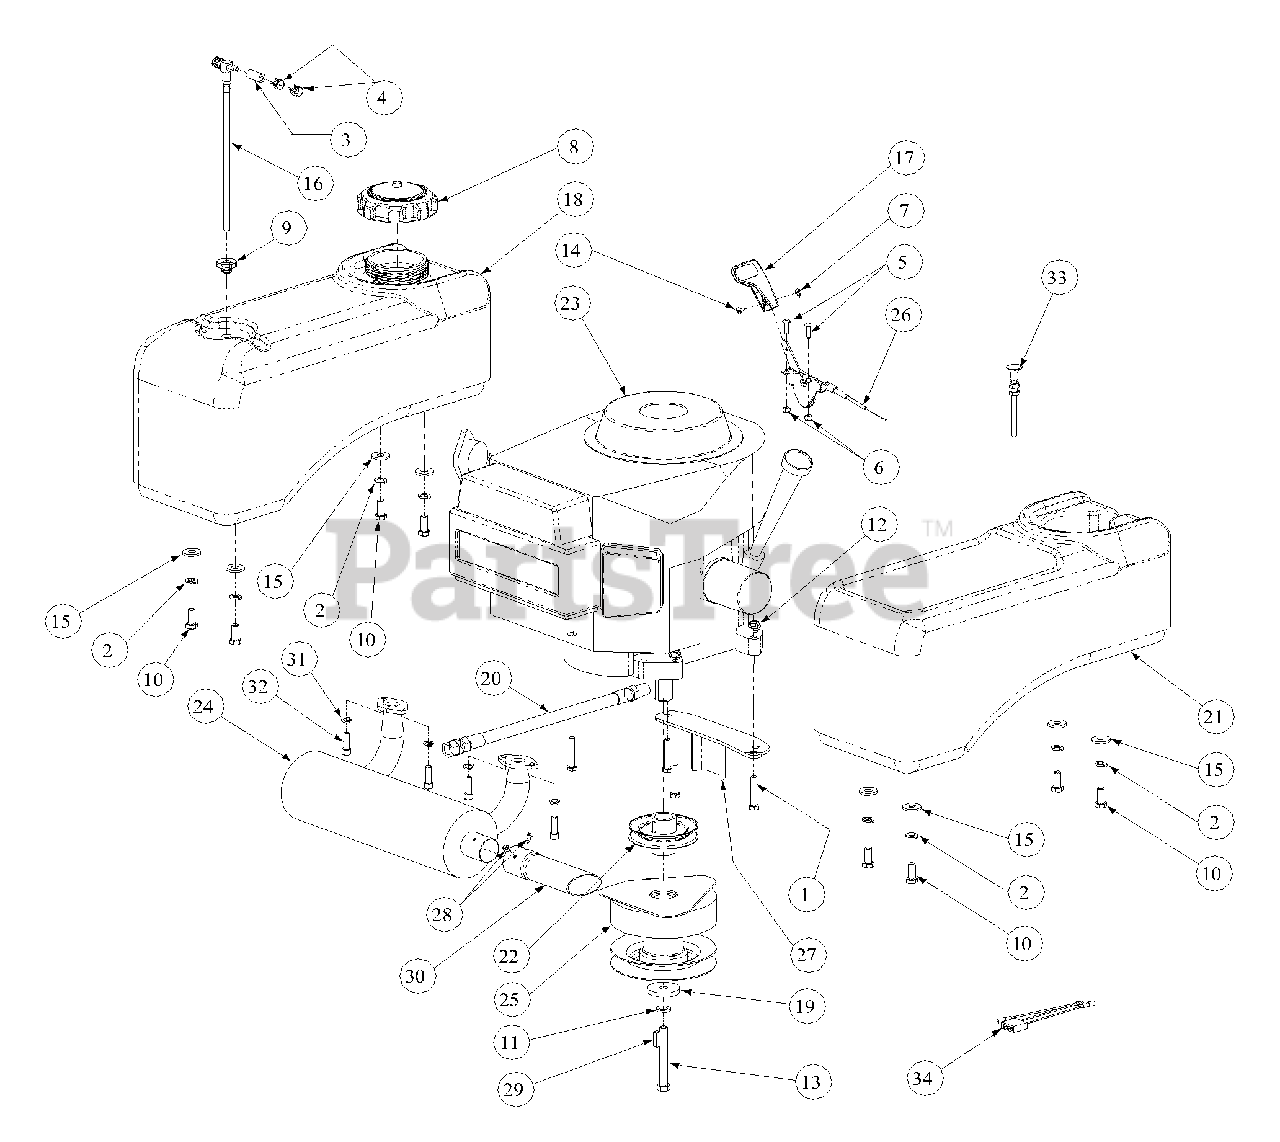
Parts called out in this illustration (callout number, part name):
1	Hex Head Cap Screw, 5/16-18 x 1-3/4
2	Lock Washer, 3/8 Zinc
3	Hose, 1/4" Fuel Line
4	Clamp, Union
5	Round Head Machine Screw, 10-32 x 3/4
6	Lock Nut, Nylon Insert, 10-32
7	Nut, w/ Star Washer
8	Fuel Cap
9	Fuel Tank Groment
10	Hex Cap Screw, 3/8-16 x .88
11	Lock Washer, 7/16
12	Lock Nut, Hex Flange, 5/16-18
13	Hex Cap Screw, 7/16-20 x 4.0
14	Machine Screw, 8-32 x .375
15	Flat Washer, .406 ID x 1.0 OD x .105
16	Fuel Pickup Fitting
17	Throttle Control Knob
18	Fuel Tank
19	Flat Washer, 7/16 ID x 1.75 OD x .250
20	Oil Drain Extension Hose
21	Utility Bin
22	Electric PTO Engine Pulley
23	18HP Twin Briggs Engine
24	Briggs Muffler
25	Ogura JD08 Electric Clutch
26	Throttle Control Cable
27	Clutch Retainer Assembly
28	Screw, 8-32 x .375, Hex Washer
29	Key, 1/4 x 1/4 x 7/8
29	Key, 1/4 x 1/4 x 2.75
30	Exhaust Pipe
31	Lock Washer, 5/16
32	Socket Head Cap Screw, 5/16-18 x 1.00
33	Choke Cable
34	Harness Adaptor
